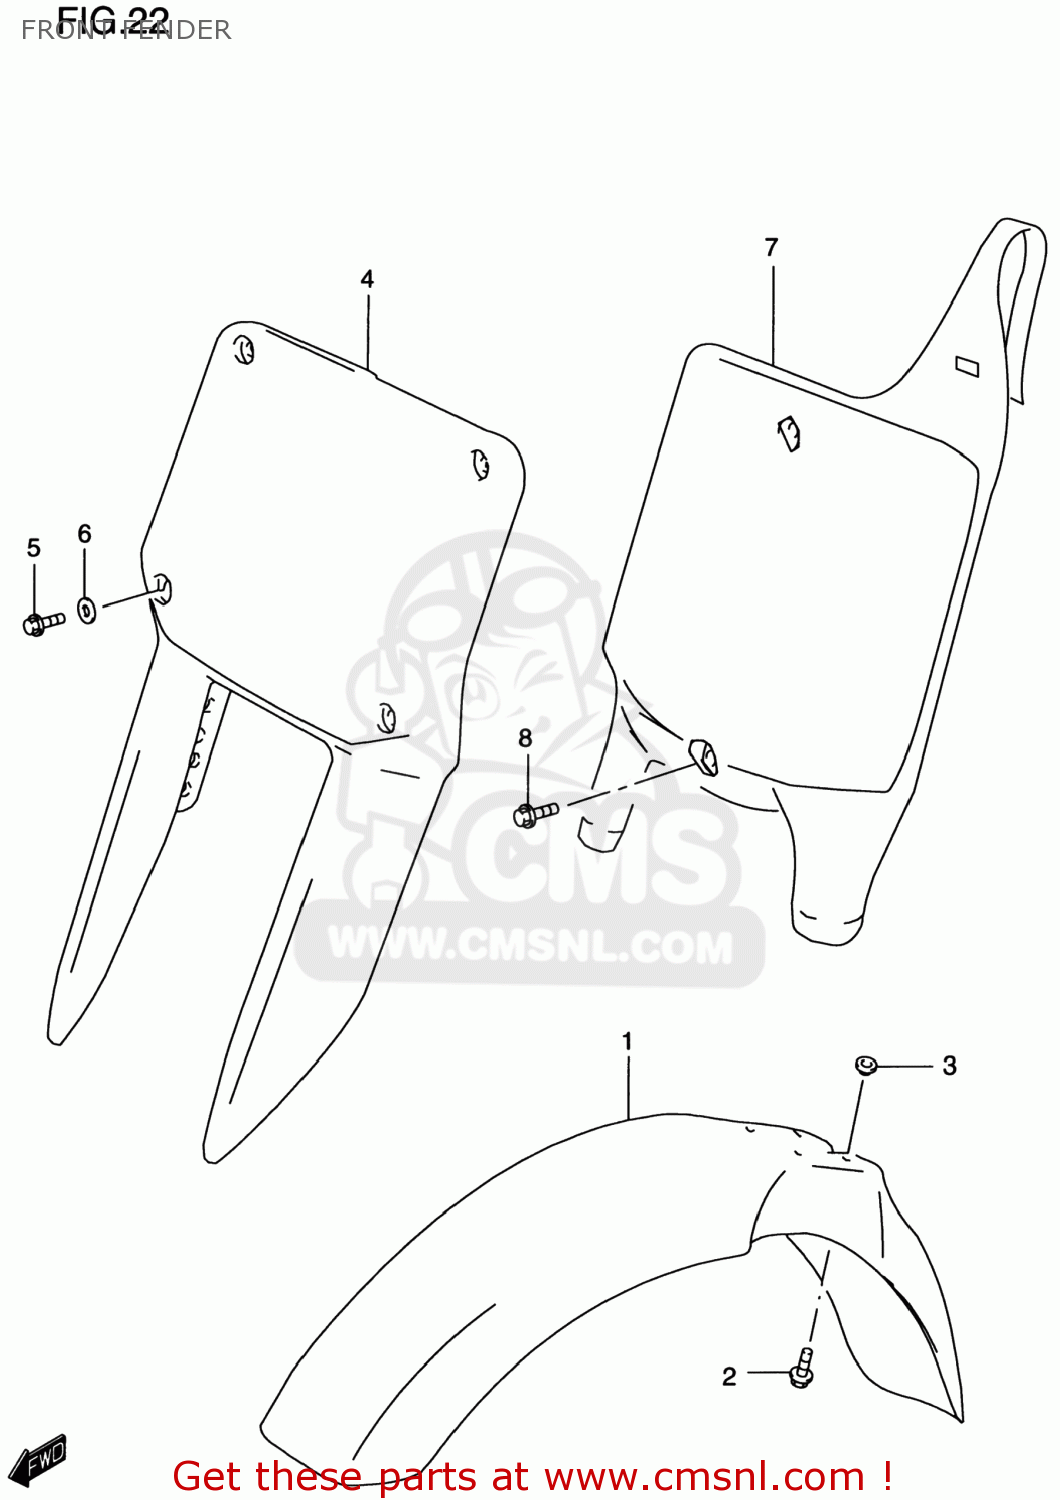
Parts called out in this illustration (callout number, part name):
1	FENDER,FRONT
2	BOLT(6X16)
3	WASHER
4	PLATE,NUMBER FR
5	BOLT
6	WASHER
7	PLATE,NUMBER,FRONT
8	BOLT(6X16)
